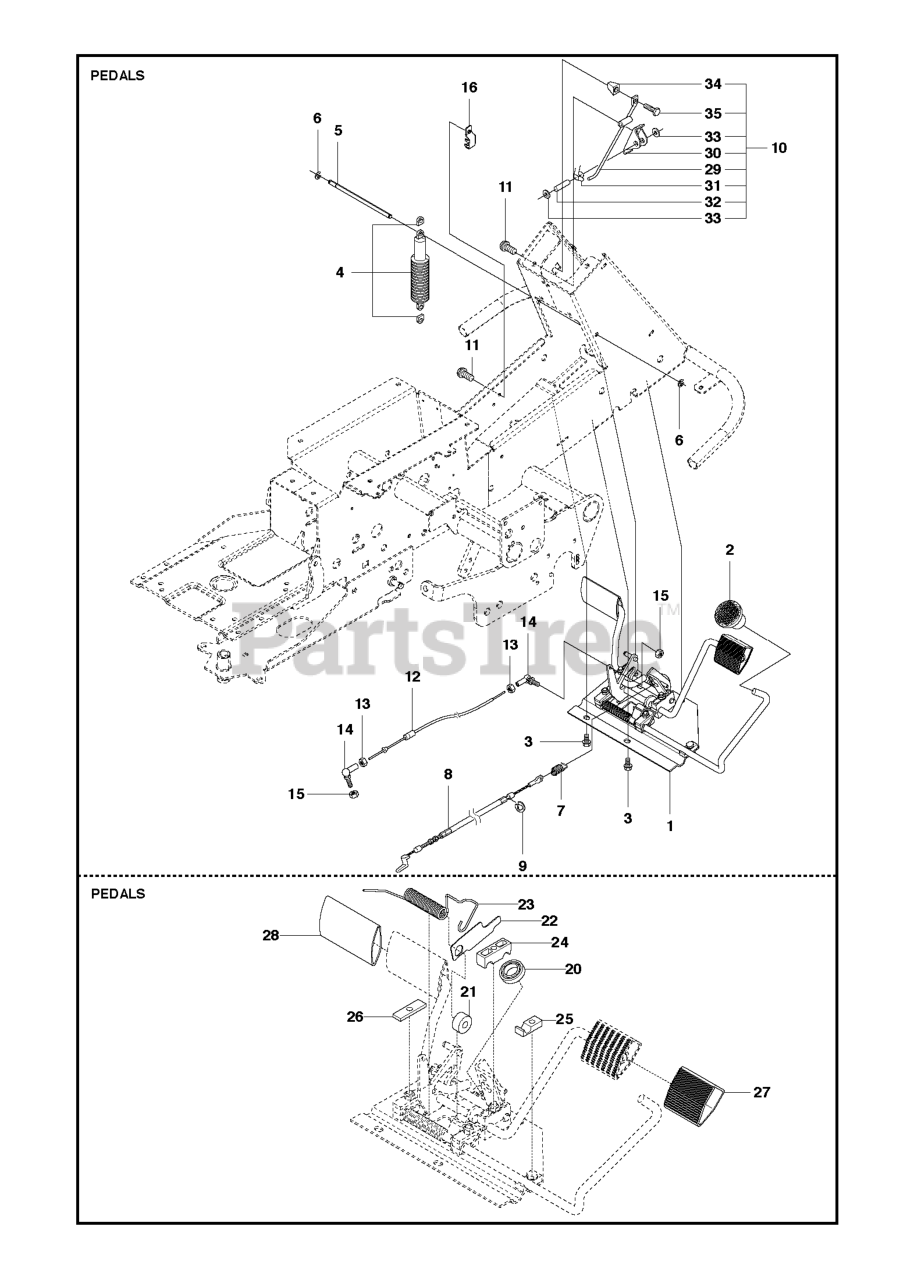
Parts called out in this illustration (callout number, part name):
1	PEDAL ASSEMBLY
2	KNOB
4	SHOCK ABSORBER
8	BRAKE WIRE
11	SCREW EHHFM
12	CONTROL CABLE
14	CONNECTOR
15	LOCKNUT M5
16	BRACKET
20	BALL BEARING 6002-2RS1
21	ROLLER
22	PLATE
23	SPRING
24	PEDAL SHAFT CLAMP
25	SUPPORT
26	PLATE
27	PEDAL RUBBER
28	PEDAL RUBBER, SF
